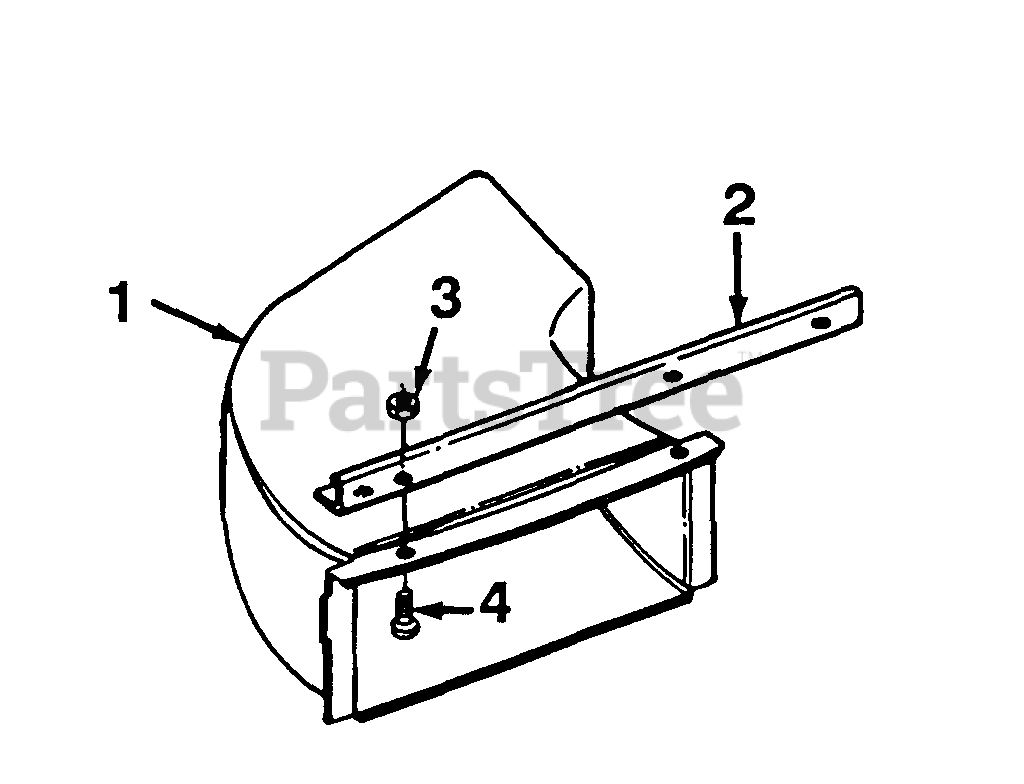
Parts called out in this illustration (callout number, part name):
1	Chute Deflector
3	Machine Screw 1/4-20 x 1/2" Lg.
4	Hex Lock Nut 1/4-20 Thd.
